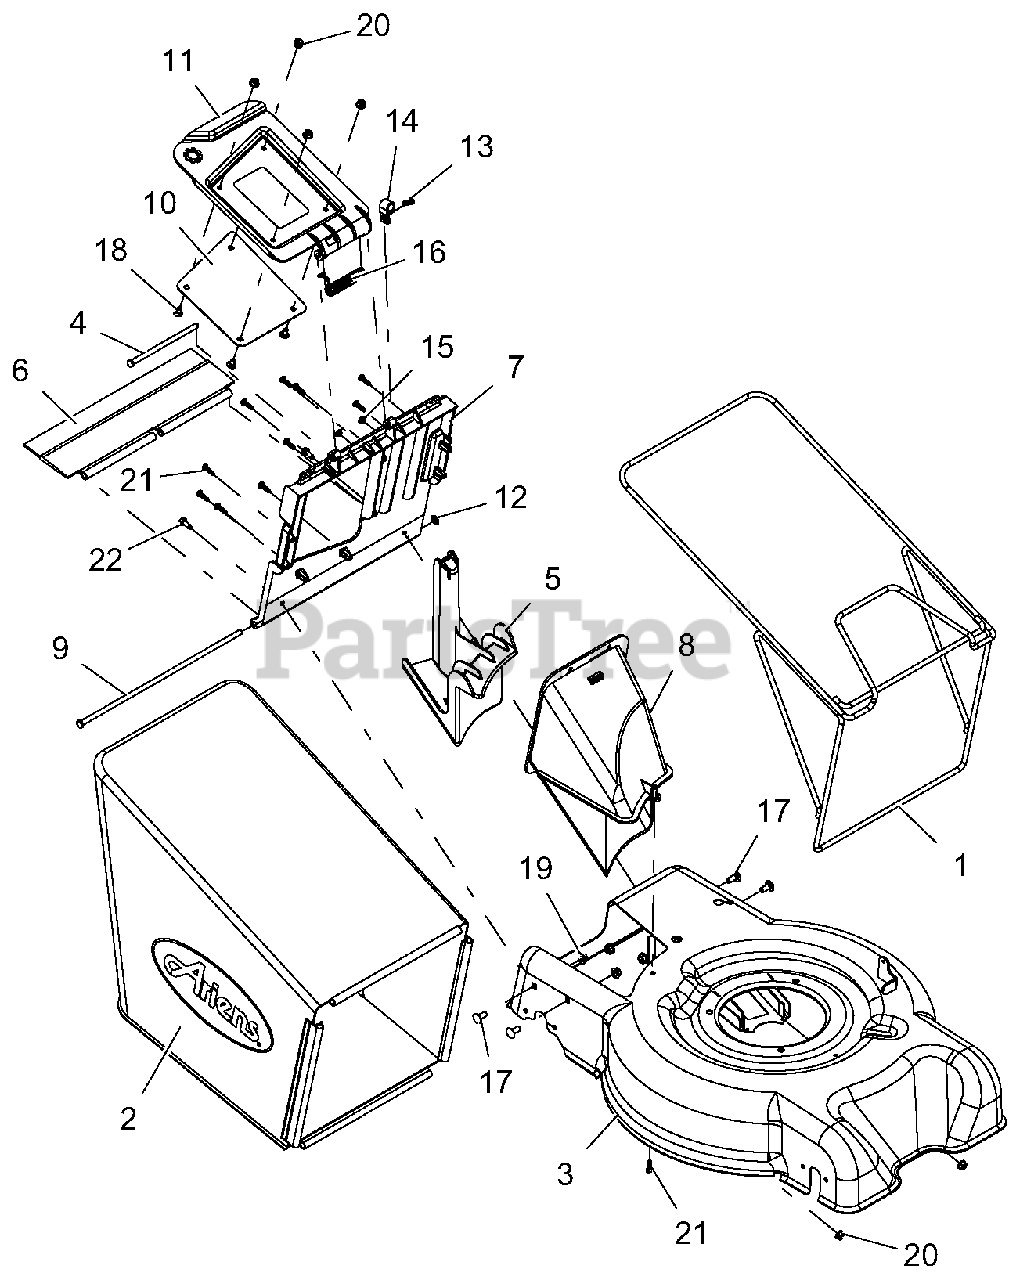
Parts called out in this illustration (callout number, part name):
1	FRAME, BAG
2	BAGGER, ARIENS LM
3	DECK W/ SAFETY DECAL
4	PIN, 5/16 X 5.80"
5	PLUG, MULCH
6	GUARD, REAR
7	HANGER, BAG
8	CHUTE, REAR DISCHARGE LM
9	ROD, REAR GUARD
10	PLATE, REAR DOOR
11	REAR DOOR W/ SAFETY DECAL
12	NUT-PUSH .312
13	PIN-HAIR INT .08X.18X1.18 YWZC
14	CLAMP, LM CABLE
15	PLUG,5/16 HOLE,.125 MATL PLSTC
16	SG-TORS .120X.68X3.09
17	@BLT-RDHDSQNK .31-18X.75 G5YZ
18	@BLT-RDHDSQNK .25-20X.50 G5YZ
19	@NUT-LK-TOP-FLG .31-18 YWZC
20	@NUT-LK-TOP-FLG .25-20 YWZC
21	SCR-TAP 12-14X.75PLSTITE @BLZC
22	@SCR-TAP .25-20X.62 HWH TR YWZ
